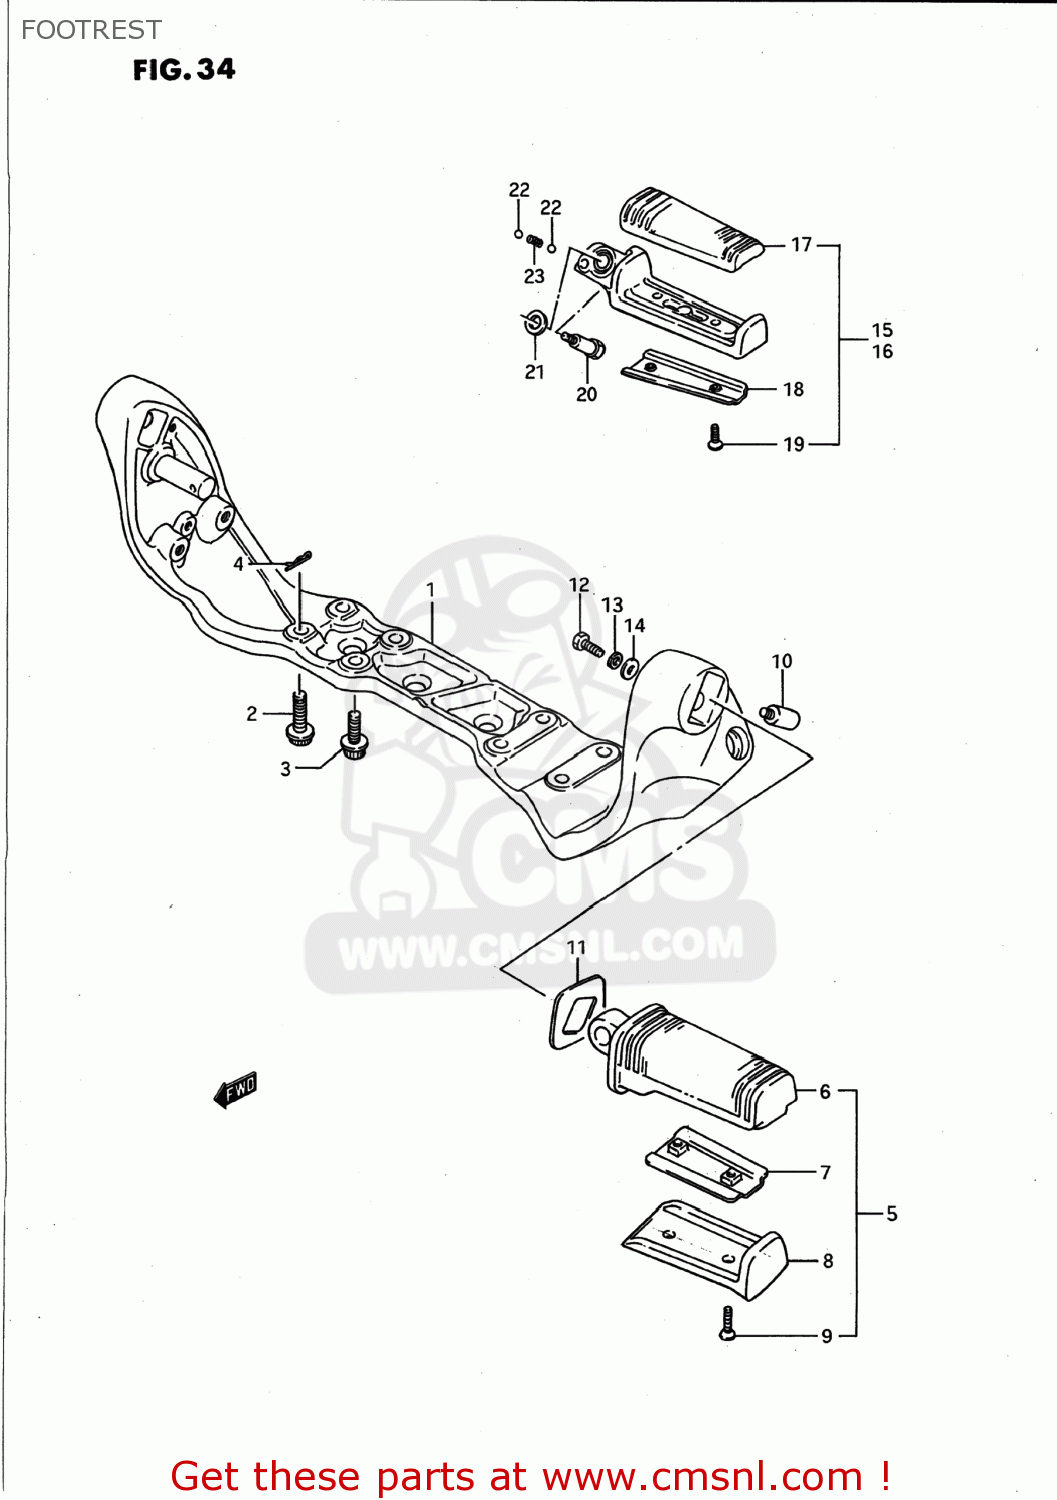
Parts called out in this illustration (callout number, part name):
1	BRACKET,FRONT FOOTREST
2	BOLT(8X25)
3	BOLT
4	SNAP
5	FOOTREST ASSEMBLY,FRONT,LEFT
6	RUBBER,FR FOOTREST
7	PLATE,RUBBER STOPPER
8	COVER,FRONT FOOTREST
9	SCREW(5X20)
10	BOLT,FRONT FOOTREST
11	WASHER,FR FOOTREST
12	BOLT
13	WASHER,LOCK
14	WASHER
15	FOOTREST ASSY RH
16	FOOTREST ASSY PILLION LH
17	RUBBER,PILLION FOOTREST
18	PLATE,RUBBER STOPPER
19	SCREW(5X16)
20	BOLT(6X34.5)
21	SHIM
22	BALL
23	SPRING
